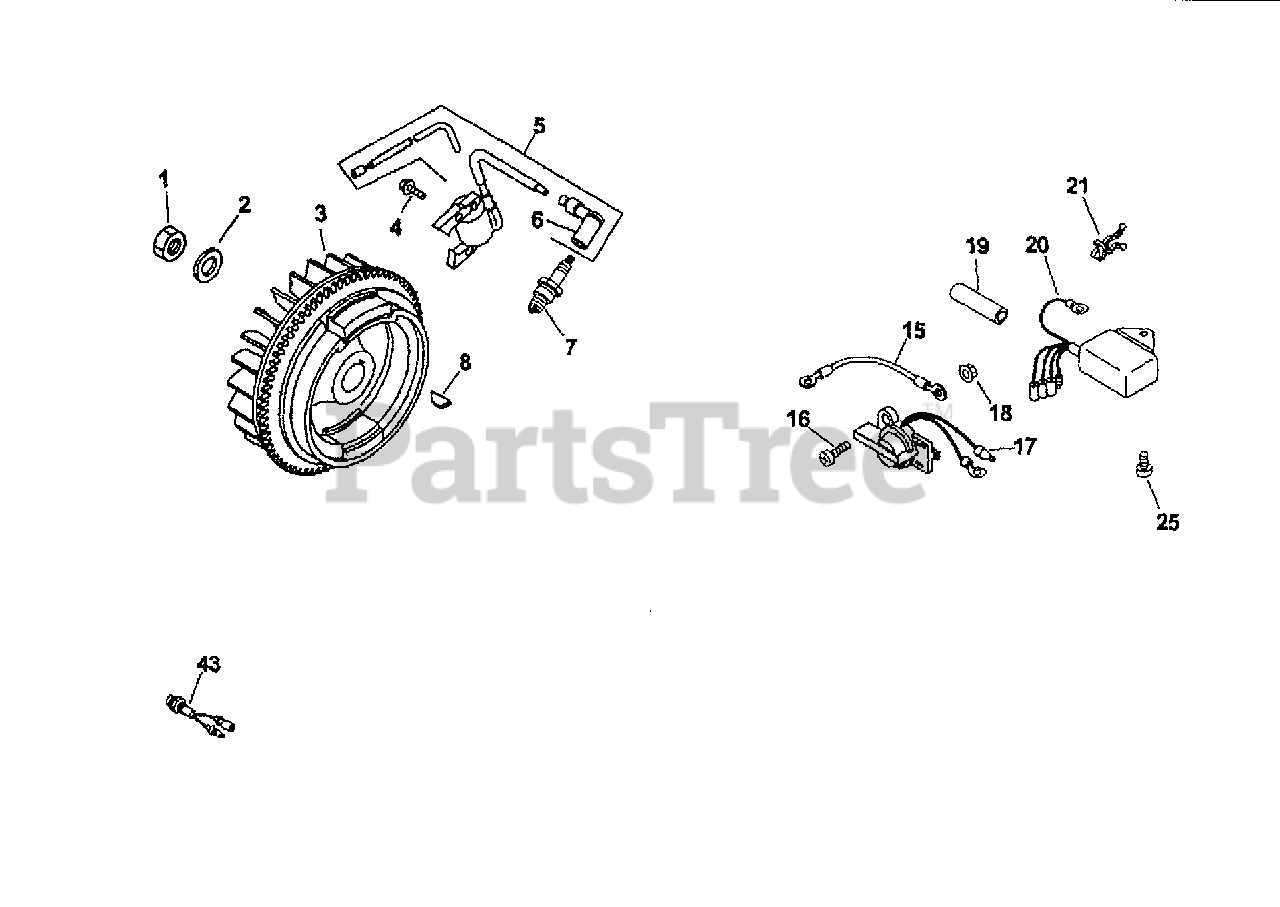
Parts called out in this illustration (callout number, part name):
1	Nut, Flywheel
2	Washer, Flywheel
5	Ignition Module
7	Plug, Spark
8	Key, Flywheel
19	Sleeve, Wiring
